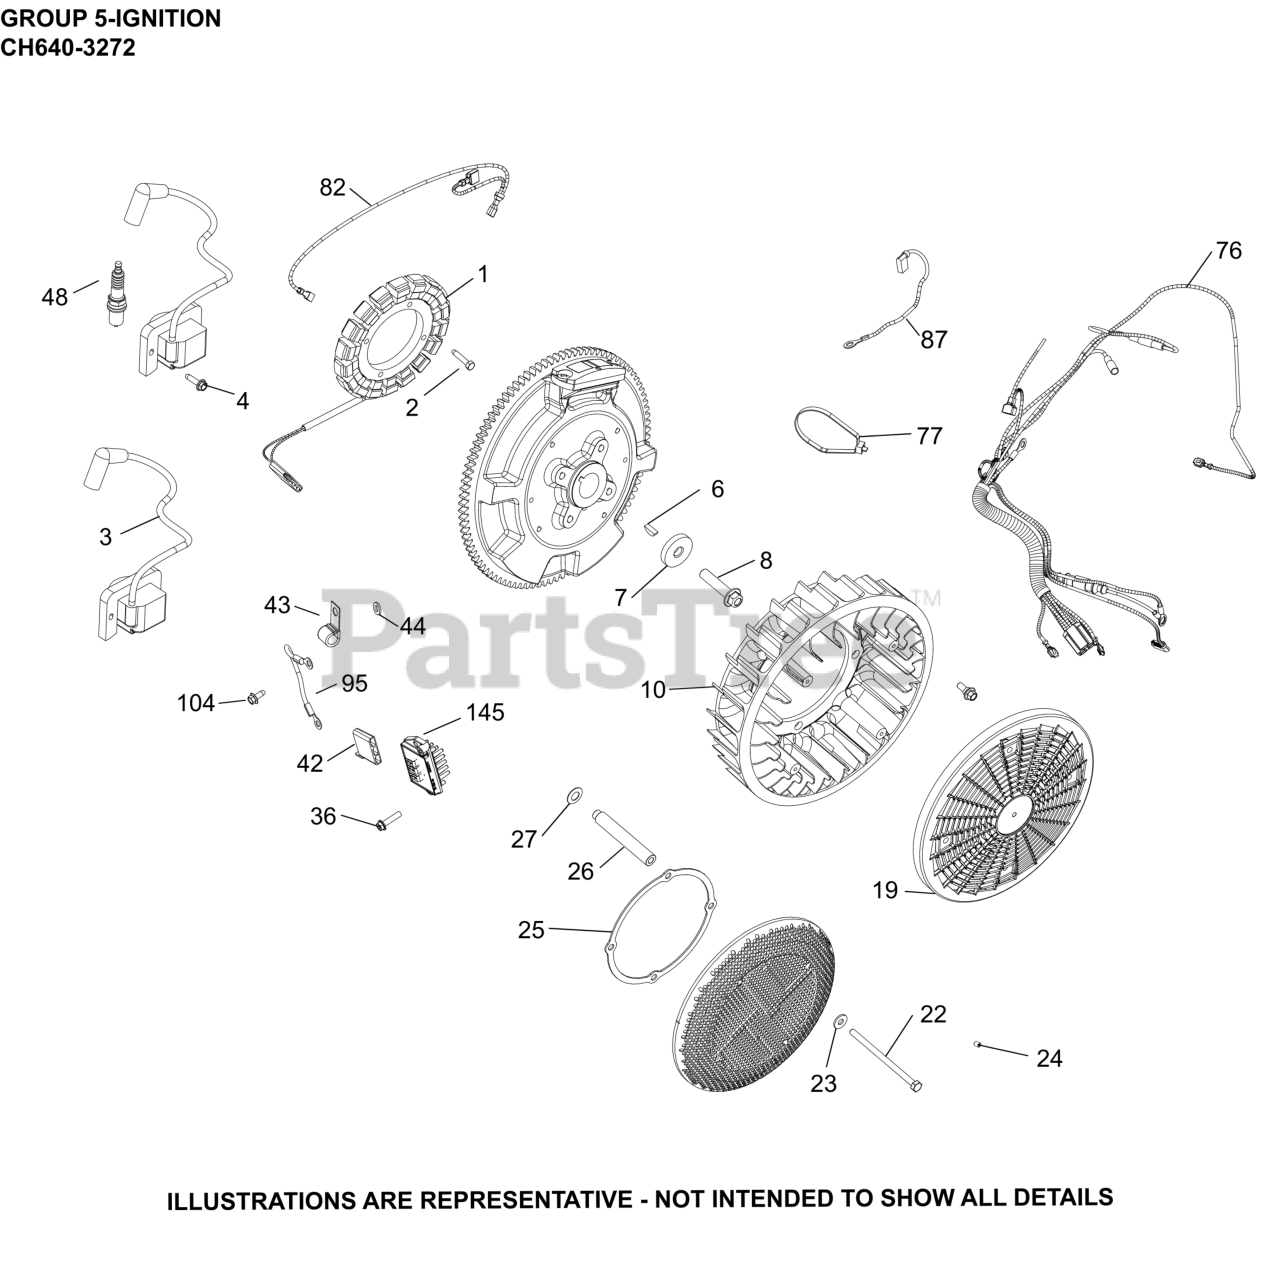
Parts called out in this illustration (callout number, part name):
1	KIT, 15 / 20 AMP STATOR
2	SCREW, THREAD FORMING
3	MODULE, EMC/RFI COMPLIANT
4	SCREW, THREAD FORMING
6	KEY, 3/16" X 5/8"
7	WASHER, FLAT
8	SCREW, HEX FLANGE
10	FAN-USE 24 755 253-S
19	SCREEN, GRASS
22	SCREW, CAP M6X1.0X99.5
23	WASHER, FLAT 1/4" (O.D. 5/8")
24	SCREW, SKT SET #10-24X1/4"
25	RING, SUPPORT
27	WASHER, SPRING 10 MM
36	SCREW, HEX FLANGE HI-LO
42	CONNECTOR
43	CLIP, CABLE
44	WASHER, FLAT 1/4" (O.D. 1/2")
48	SPARK PLUG, RFI
76	HARNESS WIRING ASSEMBLY
82	LEAD, DUPLEX
87	LEAD, 20/25 AMP B+
104	SCREW, THREAD FORMING
145	REGULATOR, RECTIFIER (20-30AMP,FW W/OVP)
NI	FLYWHEEL ASSEMBLY (LW, 22)
